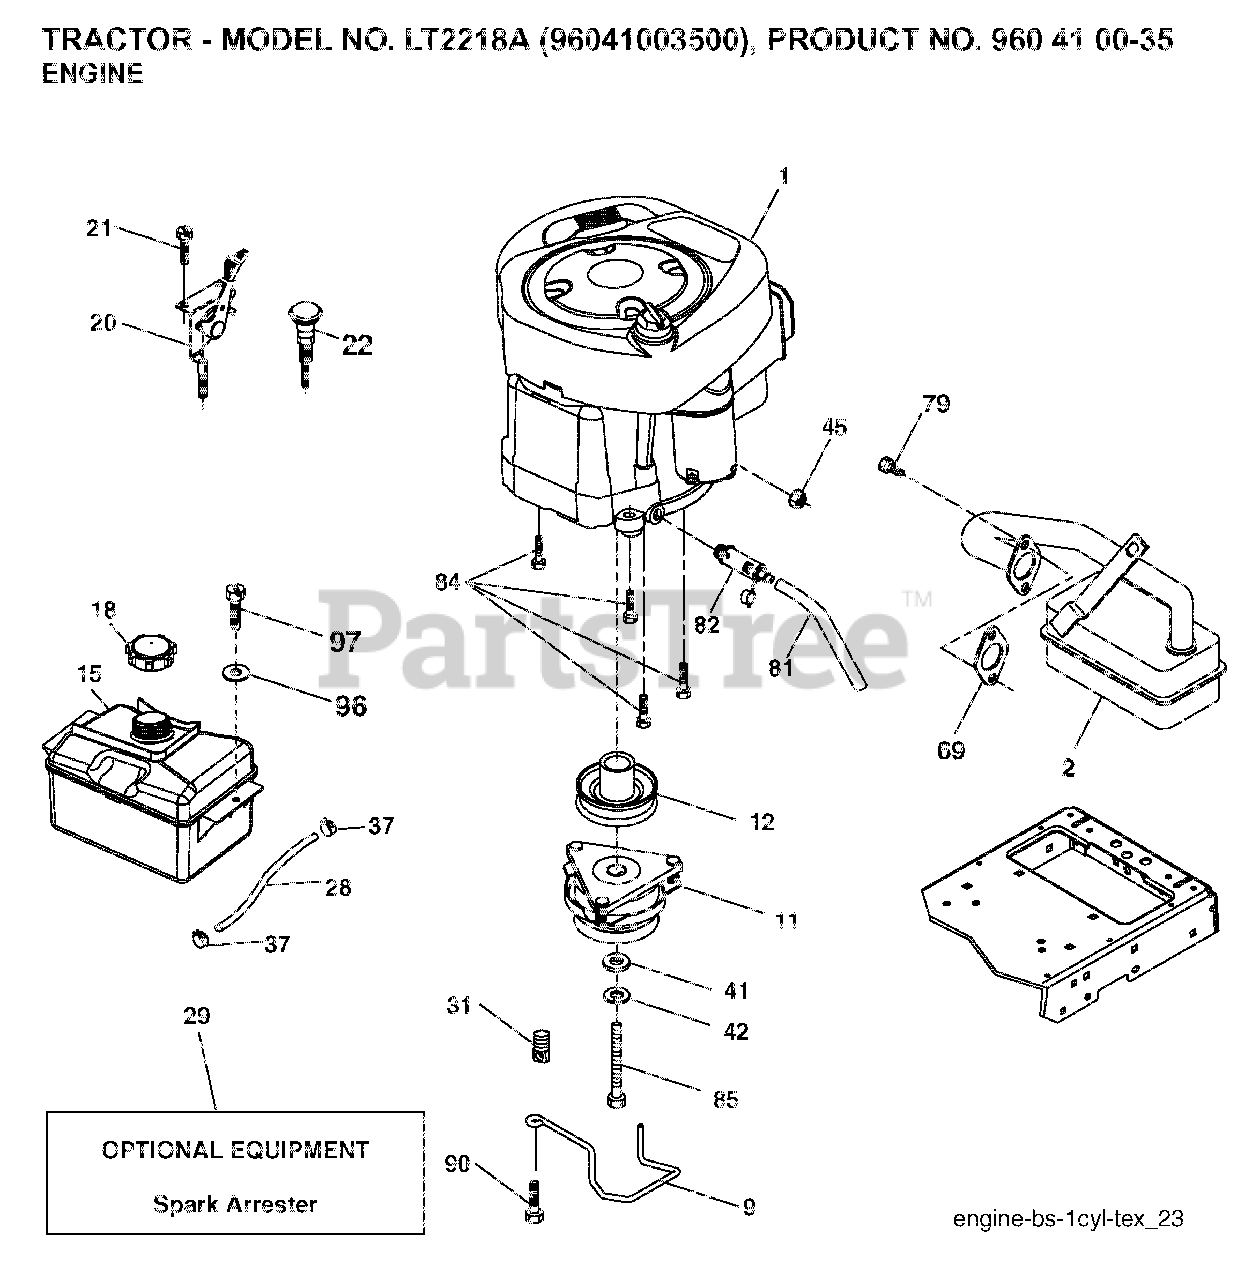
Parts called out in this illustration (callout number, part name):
9	KEEPER.BELT.ENGINE.3.25
11	CLUTCH
12	PULLEY.ASM.ENG.OGURA.3
15	TANK FUEL
18	FUEL CAP
20	CONTROL.TH/CK.C.
21	SCREW
28	LINE.FUEL.20
29	ARRESTER SPARK (OPTIONAL)
31	PUSH CLIP
37	HOSE CLAMP
42	LOCKWASHER
45	NUT
69	REPL BY 532 27 22-93
79	SCREW.SOCKET HD.5/16-1
81	TUBE, DRAIN OIL ASM.
82	PLUG DRAIN OIL EASY
84	SCREW.3/8-16
85	BOLT HEX 7/16-20X4-1/4"
90	SCREW 3/8-16X1
97	SCREW HEXWSHR 1/4-20X3/4
